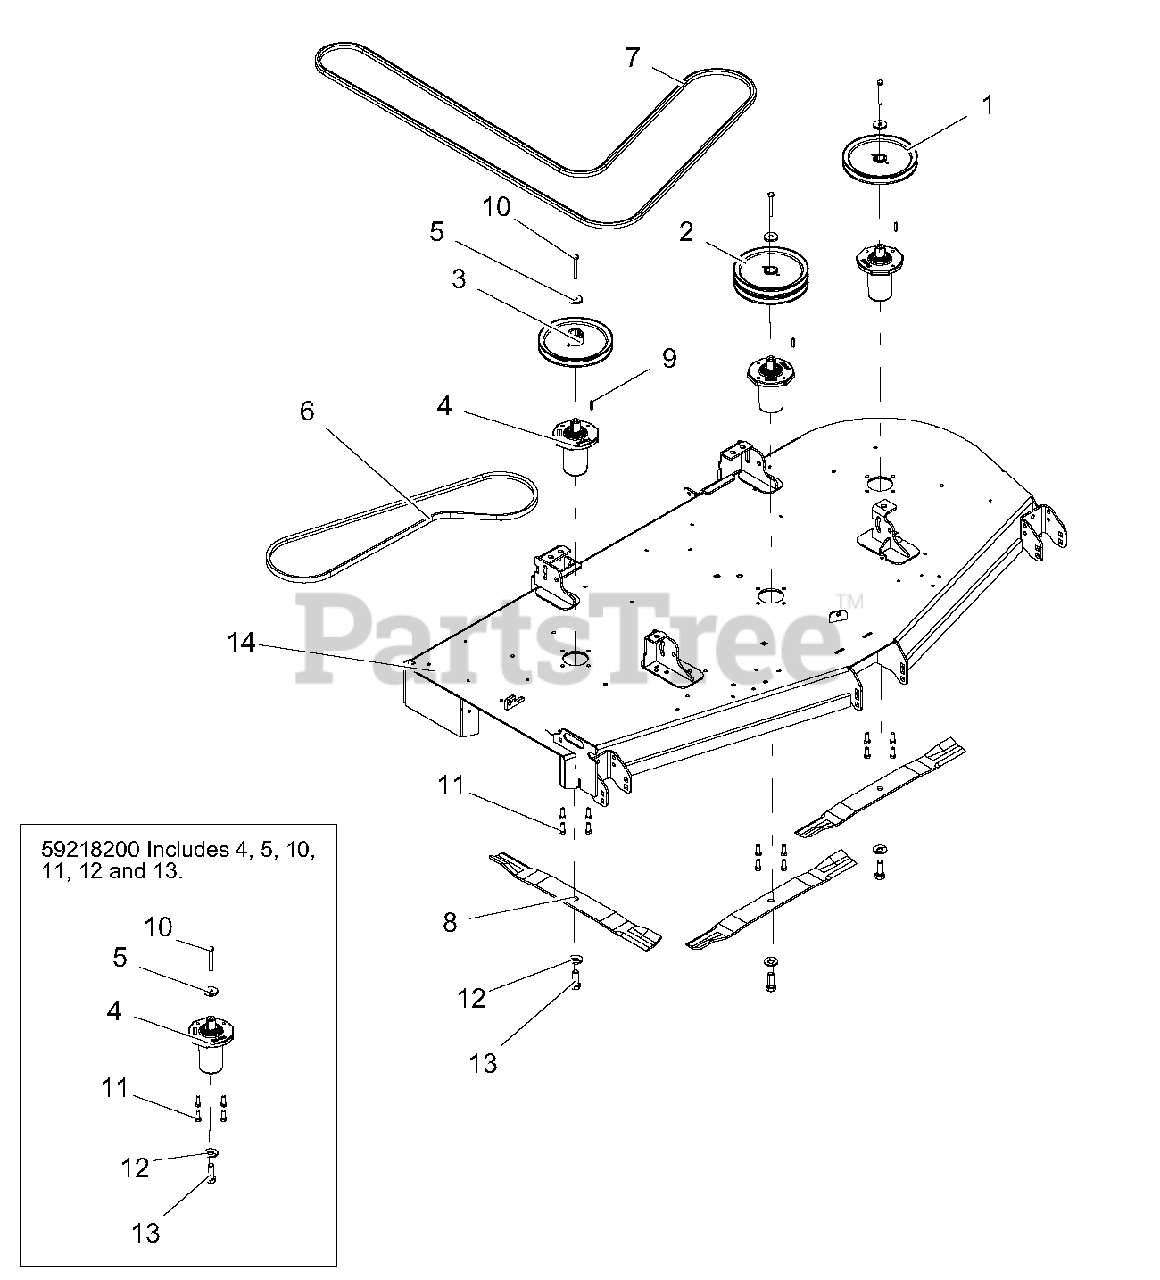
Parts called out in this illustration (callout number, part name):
1	SHEAVE-SINGLE 1.00" X 8.25" OD-BLACK
2	SHEAVE-DOUBLE 1.00"ID X 8.25"OD-BLACK
3	SHEAVE, SINGLE 1.00" ID X 8.25" OD-BLACK
4	SERVICE, ASM SPINDLE- DUCTILE
5	RETAINER, SHEAVE SPINDLE
6	V-BELT, B-COGGED
7	HEX BELT, BB-WRAPED
8	BLADE, MOWER 72" (24.5" LG)
9	KEY-SQ .250X.250X1.00 RC 40-50
10	BLT-HEX .38-16X2.75 GR8 YWZC
11	BLT-HEX .38-16X1.00 GR5 YWZC EP30
12	WSHR, BLVL .63X1.625X.14
13	BLT, HEX .62-18X1.75 GR8 YWZC
14	72" SIDE DISCH DECK W/SAFETY DECALS
